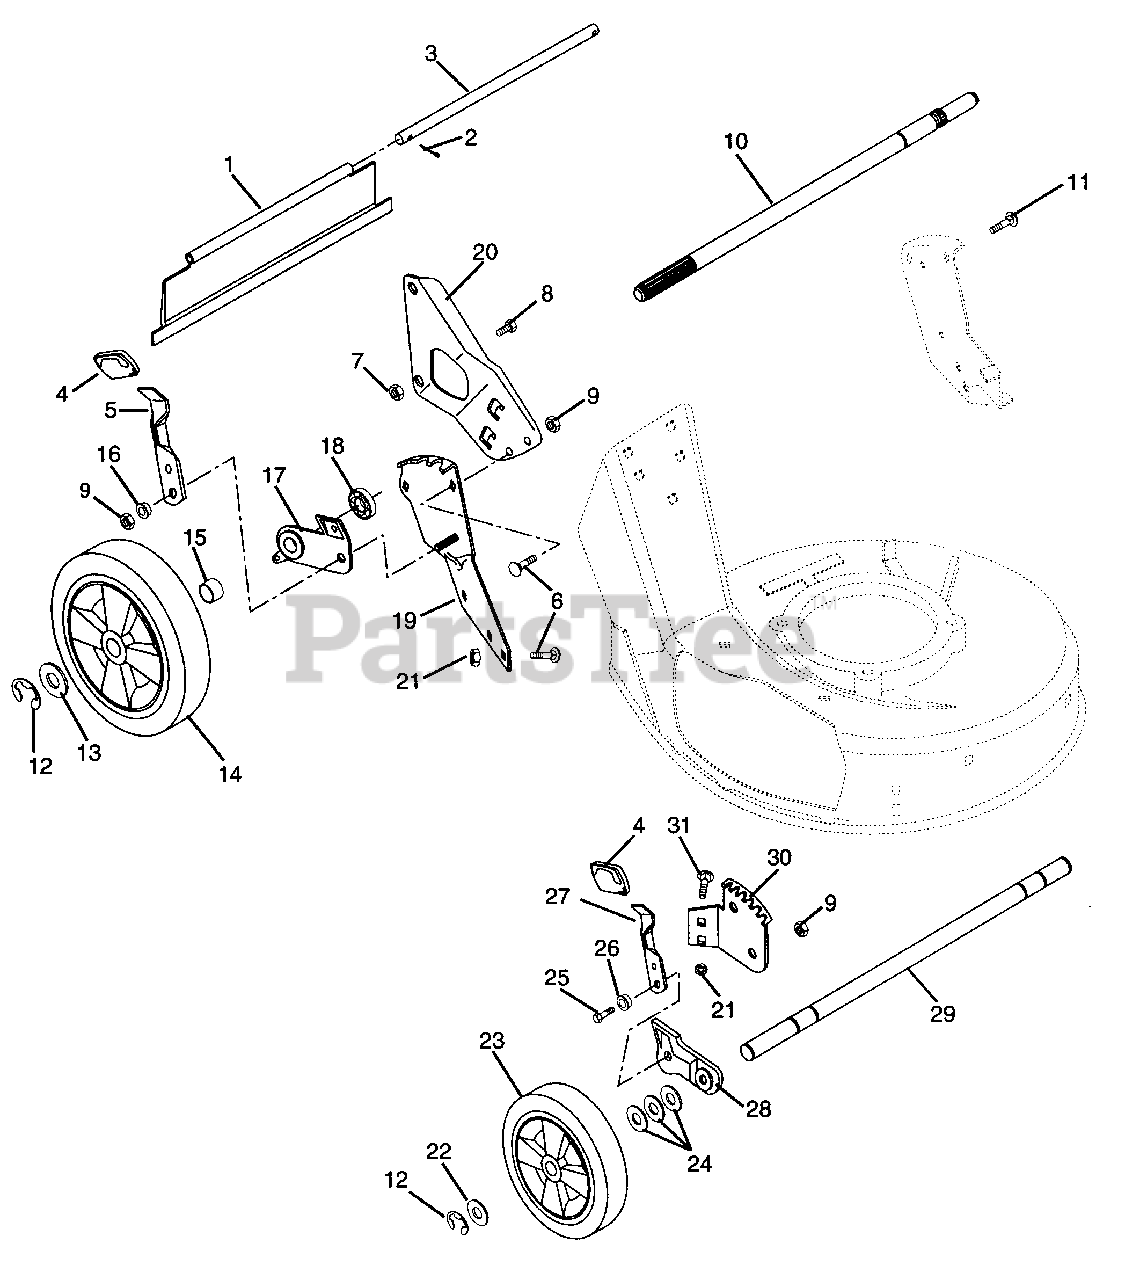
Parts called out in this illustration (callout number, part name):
1	REAR PROTECTIVE GUARD, PUSH
2	PIN-COTR .06X.50
3	ROD
4	KNOB
5	HEIGHT ADJUSTMENT LEVER
6	BLT-RDHDSQNK .312-18X.62SHTPL
7	NUT-LK-JAM-CTR .375-16 PL
8	HANDLEBAR STUD
9	NUT-LK .312-18 GR A PL
10	REAR AXLE,5/8 DIA
11	BLT-RDHDSQNK .31-18X1.0 SHT PL
12	RG-RTNG-EXT .500X.042 (E)
14	LH WHEEL
15	SPACER TUBE,PUSH LH
16	BSHG-FLG .32X.500X.344X.880
17	REAR BRACKET & BEARING ASSEMBL
18	BRG-BALL .625X1.383X.50
19	QUADRANT, REAR - L.H.
20	RH HANDLEBAR MTG. BRKT.
21	NUT-FLG. .312-18 PL
22	WSHR-FL-STL .505X.880X.072 PL
23	WHEEL
24	WSHR-FL-STL .520X.827X.062 YZ
25	BLT-HEX .31-18X.88 PL GR2
26	BSHG-FLG .32X.500X.344X.880
27	FRONT HEIGHT ADJUSTMENT LEVER
28	LEFT ADJUSTOR BRACKET ASSEMBLY
29	FRONT AXLE
30	FRONT QUADRANT, L.H.
31	BLT-RDHDSQSHNK .31-18X.50 YZ
